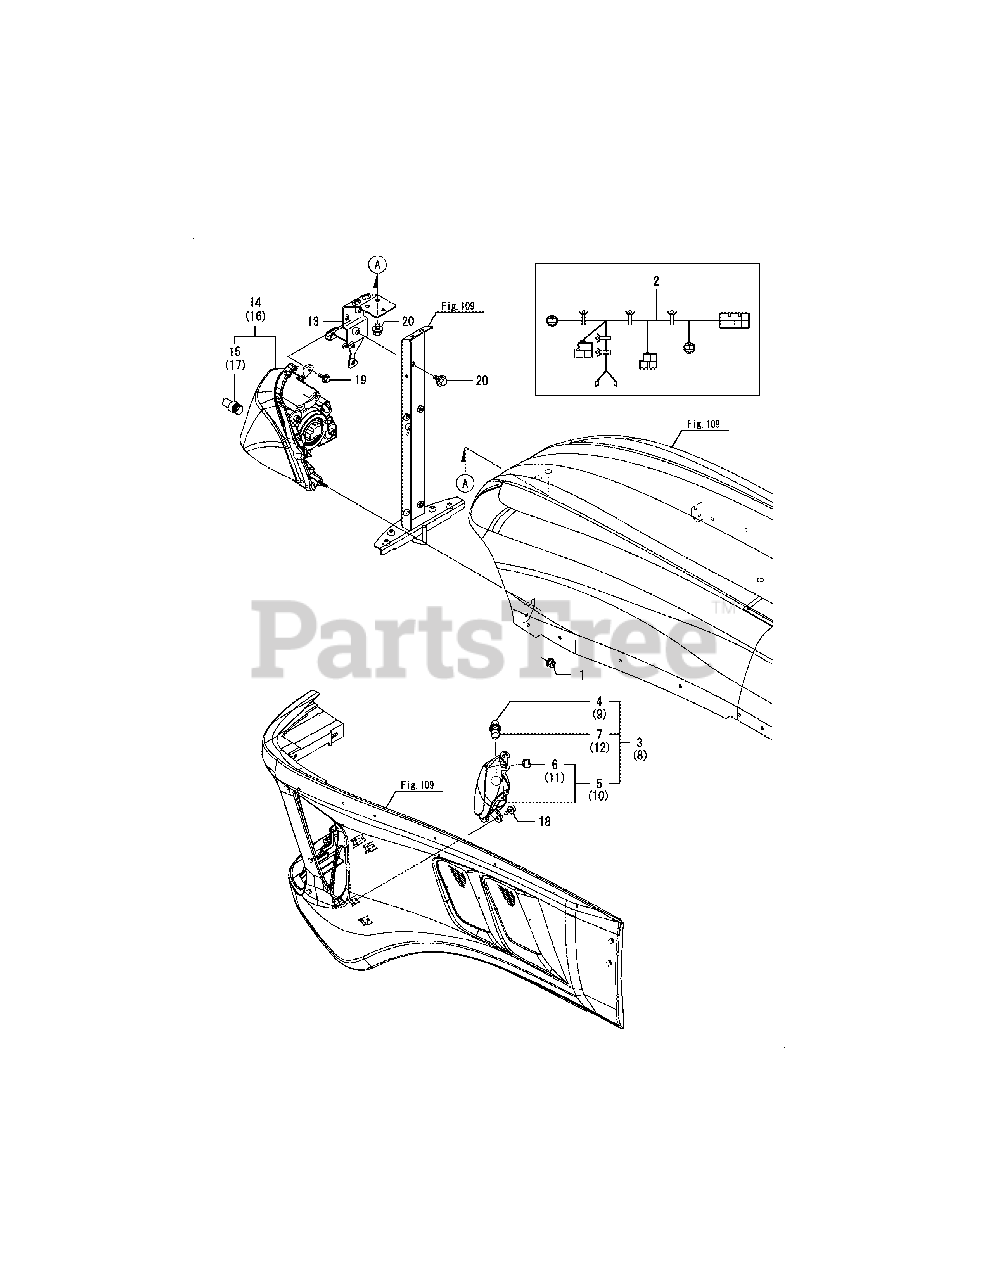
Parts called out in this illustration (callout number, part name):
1	NUT W/WASHER 6
3	LAMP ASSY, SIDE L
5	CASE ASSY,SIDELAMP L
8	LAMP ASSY, SIDE R
10	CASE ASSY,SIDELAMP R
13	STAY ASSY, HEADLAMP
14	LAMP, HEAD L CMP
16	LAMP, HEAD R CMP
19	BOLT M 6X 20 PLATED
20	BOLT M 8X 12 PLATED
